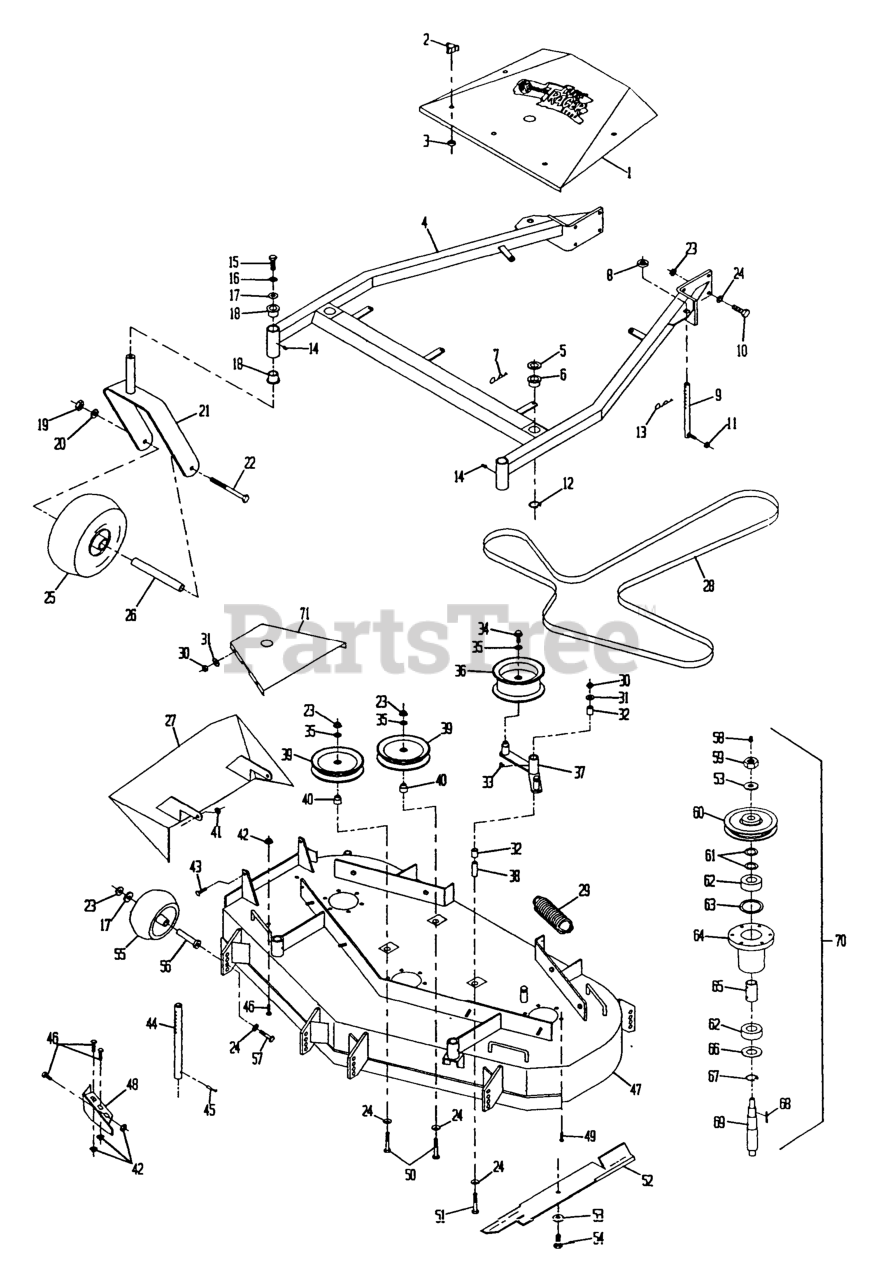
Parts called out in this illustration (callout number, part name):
2	KNOB-3 PRONG
4	SUPPORT,DECK W/BUSHINGS
5	WASHER-FLAT
6	BUSHING-DECK
13	PIN,HAIR COTTER
18	BEARING-FLANGED
27	WLD,CHUTE DISCHARGE
28	BELT,DECK DRIVE
32	SLEEVE-BEARING
38	BUSHING-PIVOT, IDLER
39	PULLEY-IDLER
40	BUSHING-IDLER
44	ROD,DECK SUPPORT
47	ASM,DECK W/DECALS TTHP52
48	WLD,BAFFLE DISCHARGE
49	SCRW,TPTTE HH
51	SCREW-HH
53	WASHER-SPRING
55	ROLLER-SCALP, ANTI
56	BUSHING-ROLLER
60	SHEAVE,W/HUB 5.72
61	WASHER-SPACER
62	BEARING,HD SPINDLE
64	HOUSING,BEARING
65	SPACER,BEARING
66	SEAL,MECHANICAL DUST
67	RING,SNAP WLDS N5000-244
68	KEY-RECTANGLE
